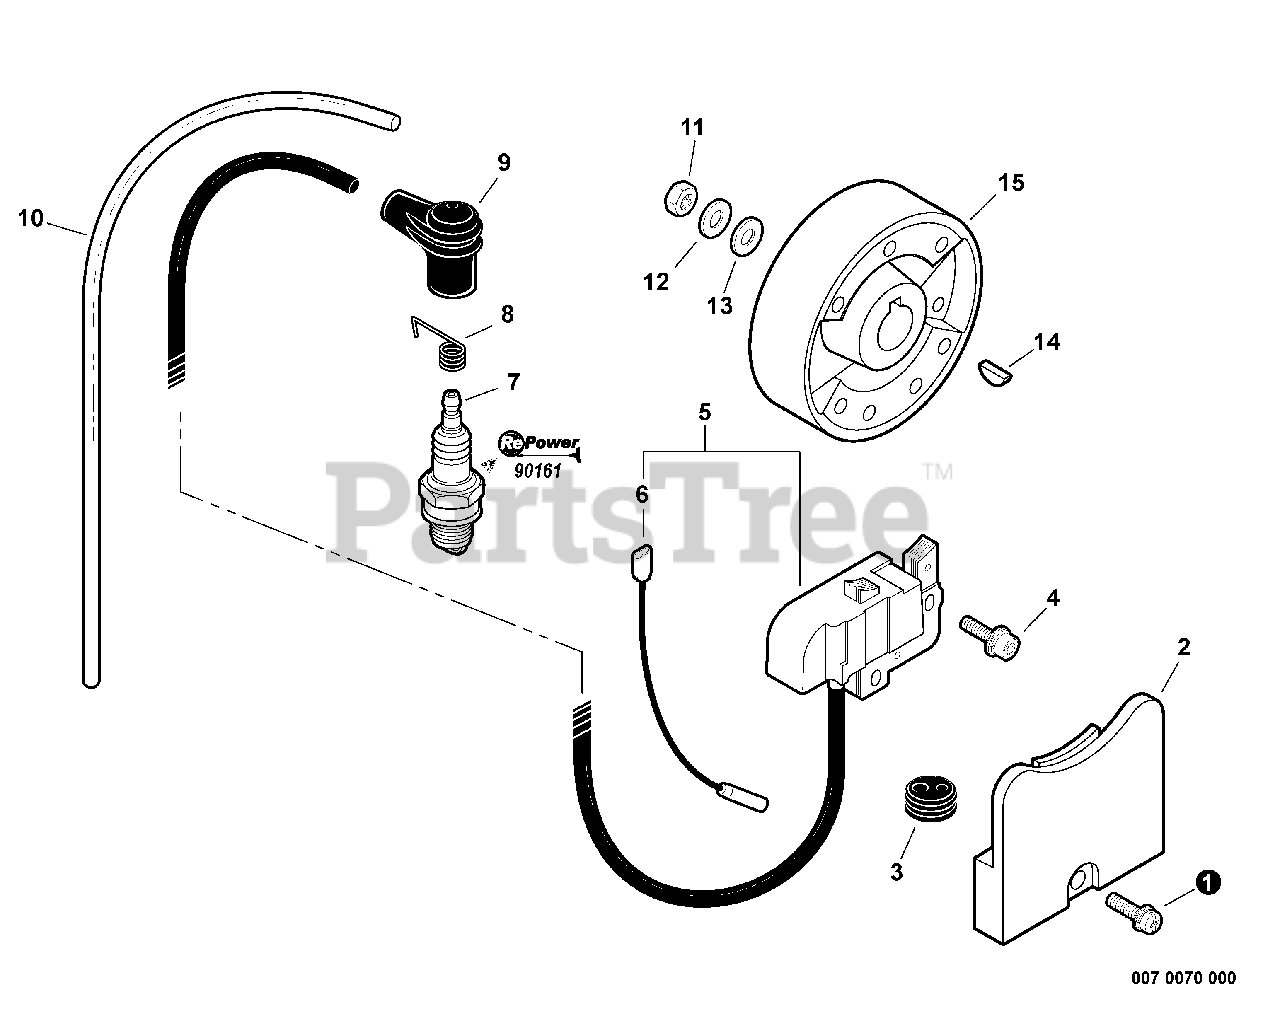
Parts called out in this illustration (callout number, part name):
1	SCREW - 5X18
2	COVER, DUST
4	SCREW - 5X18
5	COIL, IGNITION
6	LEAD - IGNITION
7	SPARK PLUG -- BPM-7Y
7	SPARK PLUG -- BPMR-7A
8	TERMINAL, SPARK PLUG CAP
9	CAP, SPARK PLUG
10	TUBE - VINYL
11	NUT - 10
12	LOCKWASHER - 10
13	WASHER - 10
14	KEY - 3X14
15	FLYWHEEL
16	RePower TUNE-UP KIT
